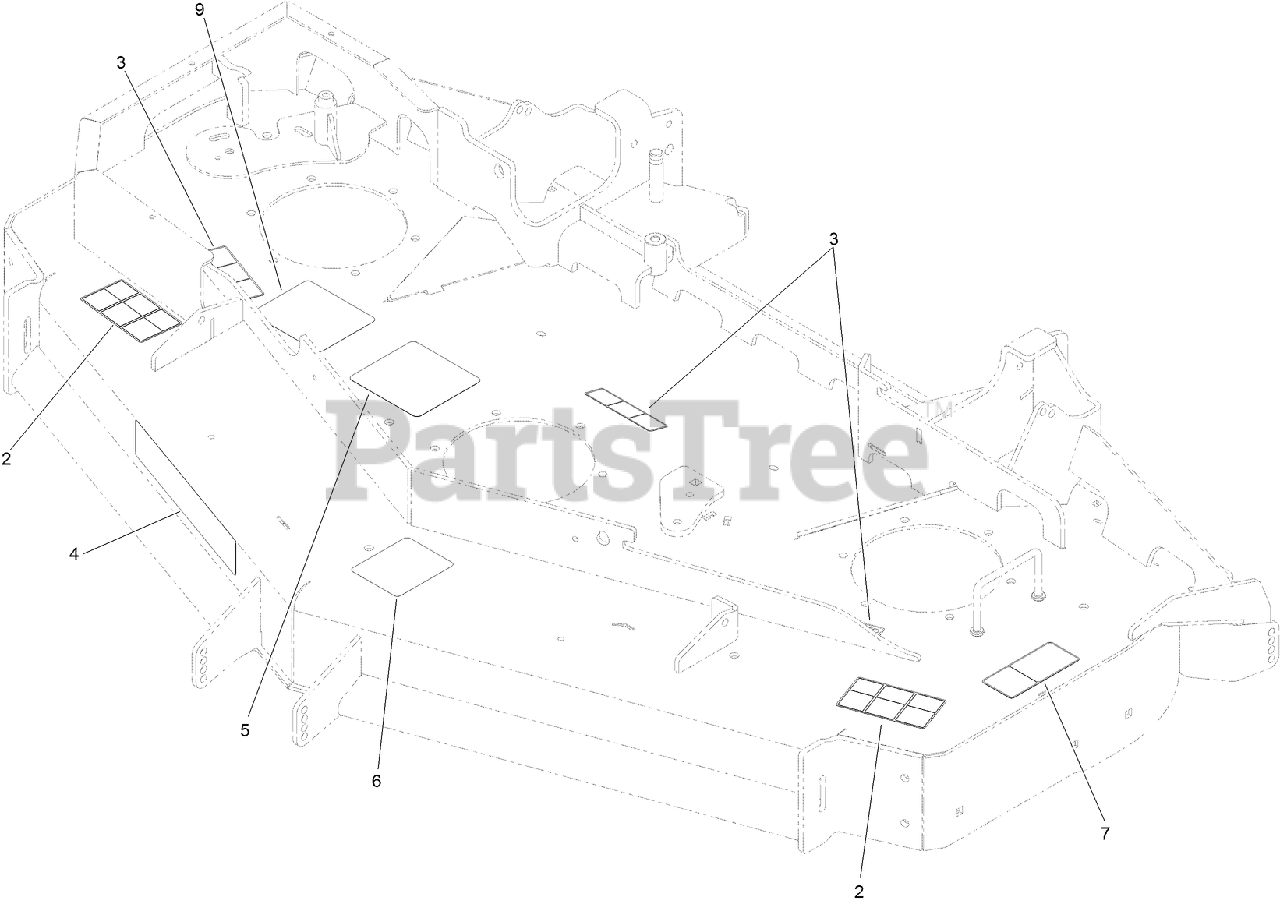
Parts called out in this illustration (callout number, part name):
2	DECAL-DANGER
3	DECAL-MISSING, COVER
5	DECAL-ROUTING, DECK BELT
6	DECAL-ROLLER, ANTI-SCALP
7	DECAL-TORQUE, BLADE BOLT
9	DECAL-SPINDLE, COUNTER ROTATING
